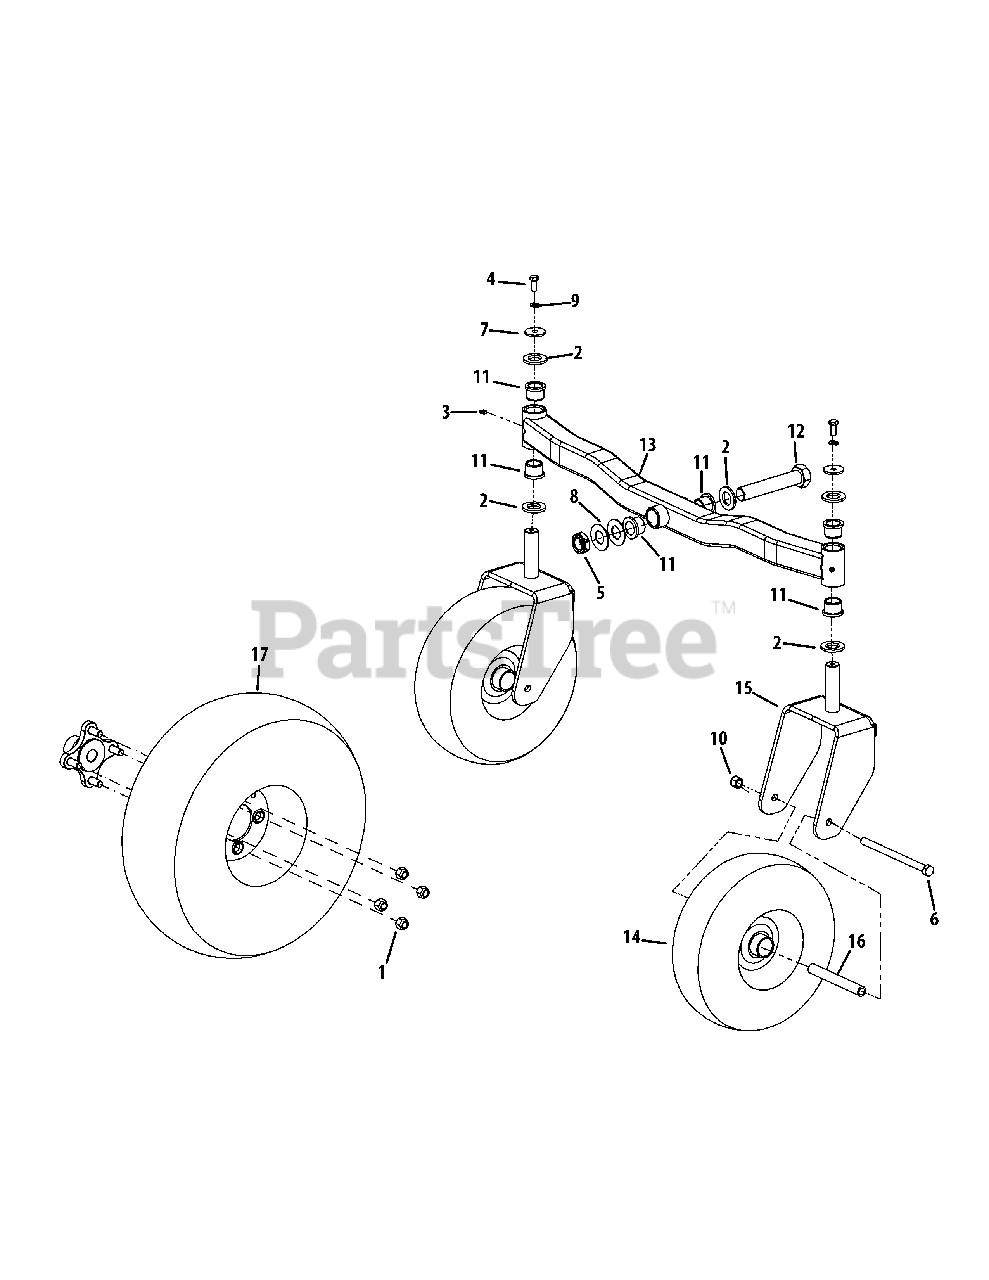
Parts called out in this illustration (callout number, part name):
1	Lug Nut, 1/2-20
2	Washer, 1.00 x 1.75 x .172
3	Grease Fitting, 1/4-28
4	Hex Screw, 3/8-16 x .880
5	Jam Nut, 1-14
6	Hex Screw, 1/2-20 x 7.50
7	Washer, .390 x 1.50 x .122
8	Washer, 1.00 x :2.00 x .075
9	Lock Washer, 3/8
10	Nylock Nut, 1/2-20
11	Flange Bearing, 1.001 x 1.25
12	Hex Screw, 1-14 x 5.5
13	Front Axle Weldment
14	Wheel Assembly, 13 x 5-6
15	Castor Wheel Mount Bracket Assy.
16	Spacer, .51 x .75 x 5.825
17	Wheel Assy., 20 x 8-10 (48" Deck)
17	Wheel Assy, 20 x 10-10 (54" Deck
